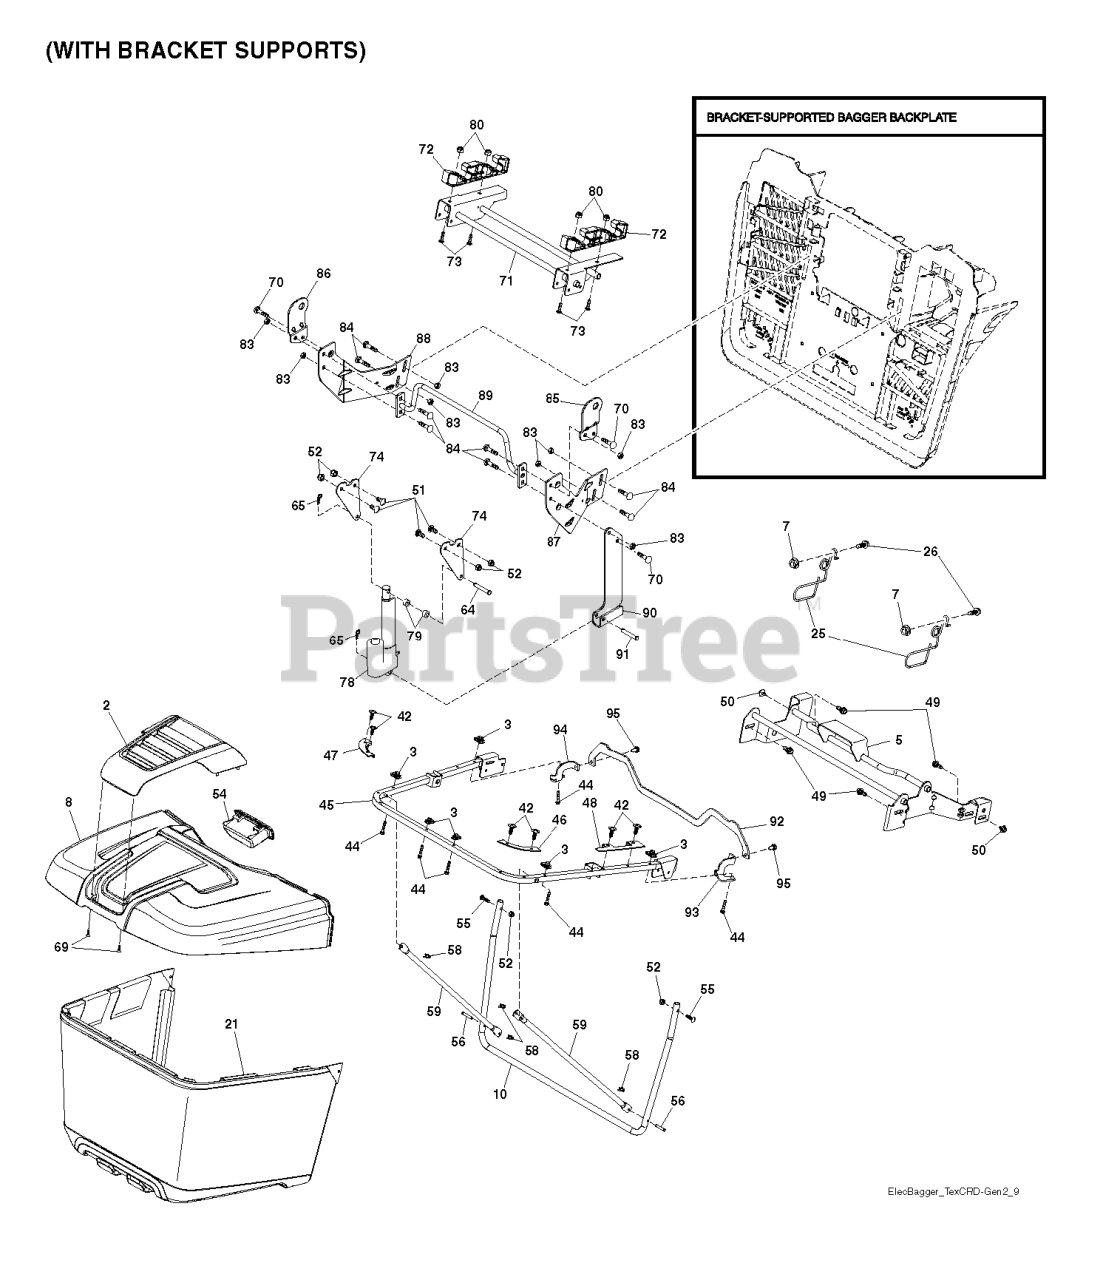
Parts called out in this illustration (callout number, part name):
2	APPLIQUE.BAGGER
3	1/4-20 U NUT
7	NUT T
10	FRAME TEX_CRD_GEN2 BAGGER FRAM
21	BAG FRAME BAGGER ASSEMBLY. HUS
25	LATCH LATCH. BAG. CRD GEN 2
26	SCREW HEX CRT
42	CLIP CHRISTMAS TREE CLIP
45	FRAME TEX_CRD_GEN2 UPPER U FRA
46	CONNECTOR RIGHT BAGGER CORNER
47	CONNECTOR LEFT BAGGER CORNER C
48	BAFFLE BAGGER SIDE CLOSE-OUT
49	BOLT, SHOULDER 5/16-18
50	BOLT.5/16-18UNCX3/4 W/SEMS.BLK
51	BOLT.CARR.SQNK.5/16-18UNC.X3/4
52	NUT.71038.31-18.HEX.NYLOCK
54	HANDLE BAGGER TOP FRONT HANDLE
55	BOLT
56	PIN.CLEVIS.183
58	RETAINER CLIP PM
59	TUBE BAGGER SPREADER TUBE, TEX
65	RETAINER M
69	SCREW,#8.FLAT.HEAD.DRILL.TIP
70	SCREW, 3/8-16X3/4
73	BOLT.CARRIAGE.5/16-18
79	SPACER.NYLON.75" X .4375
80	NUT LOCK HEX FLANGE 5/16-18
83	NUT
84	BOLT D
85	BRACKET.RH.PIVOT.ELE.DUMPX431
86	BRACKET.LH.PIVOT.ELE.DUMPX431
87	BRACKET.RH.MID.SUP.BAG.TEX.CRD
88	BRACKET.LH.MID.SUP.BAG.TEX.CRD
89	TUBE.WELD.OFSET.STRUT.BAG.X431
90	BRACKET.ELE.DUMP.ACT.BAG.X431
91	PIN.CLEVIS.(.375 X 1.25)
92	BRACKET.PNT.BAGGER.TOP.SUPPORT
93	BRACKET.PNT.RH.SUPPORT.ATTACH
94	BRACKET.PNT.LH.SUPPORT.ATTACH
95	SCREW
